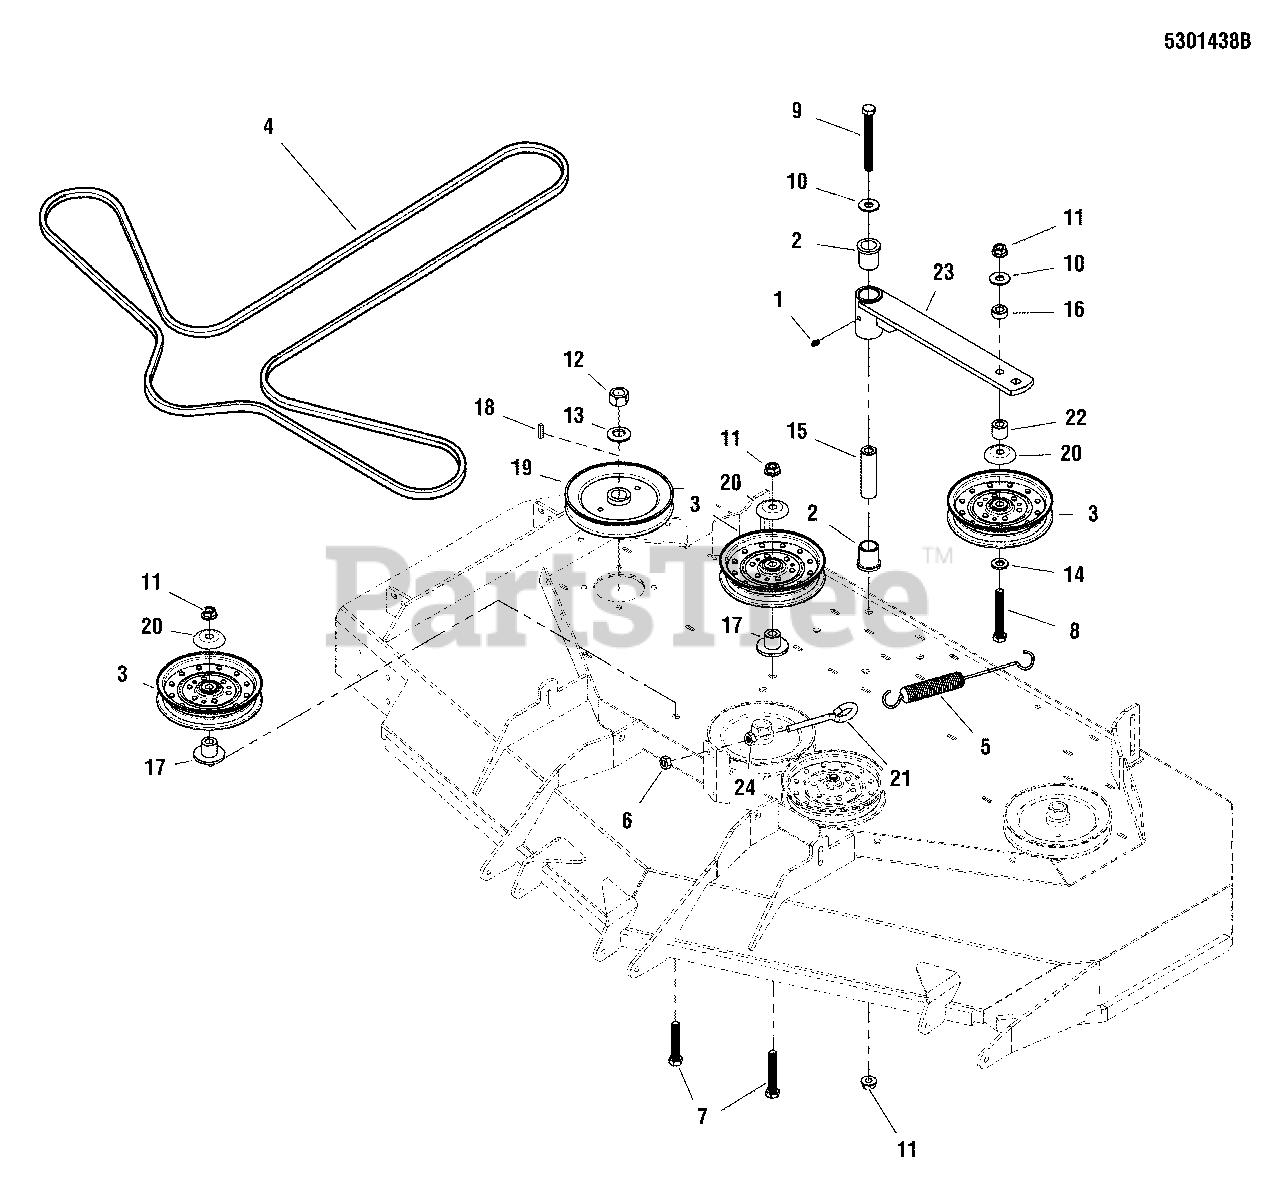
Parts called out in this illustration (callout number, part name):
1	GREASE FITTING, 1/4-28 STRAIGHT
2	BUSHING, FLANGE
3	*PULLEY, FLAT IDLER, 6-3/4"
4	BELT, 5V, 175.90EL, LG ARAMID, WRPD, RC
5	SPRING-EXTENSION, SWIVEL END
6	NUT, 3/8-16 HEX NYLOCK FLANGE
7	BOLT, 1/2-13 X 3 GD5
8	BOLT, 1/2-13 X 3-1/2 GD5
9	BOLT, 1/2-13 X 4-1/2 GD5
10	WASHER, 1/2 USS
11	NUT, 1/2-13 HEX NYLOCK FLANGE
12	NUT, 3/4-16 HEX
13	WASHER, 3/4 BELLEVILLE
14	WASHER, 1/2 GD9 YZ
15	SPACER, .52 X 1.00 X 3.50
16	SPACER, .52 X 1.00 X .44
17	WELD, MOUNT, IDLER
18	KEY, 1/4 SQ. X 1-1/4
19	PULLEY, 6.5 EOD X 25MM, SPLIT
20	SHIELD, PULLEY BEARING
21	EYE BOLT, 3/8-16 X 5, 1 EYE
22	SPACER, .52 X 1.00 X .88
23	ASSM, IDLER ARM - BLK - 5407039A (SV)
24	NUT, 3/8-16 HEX JAM
